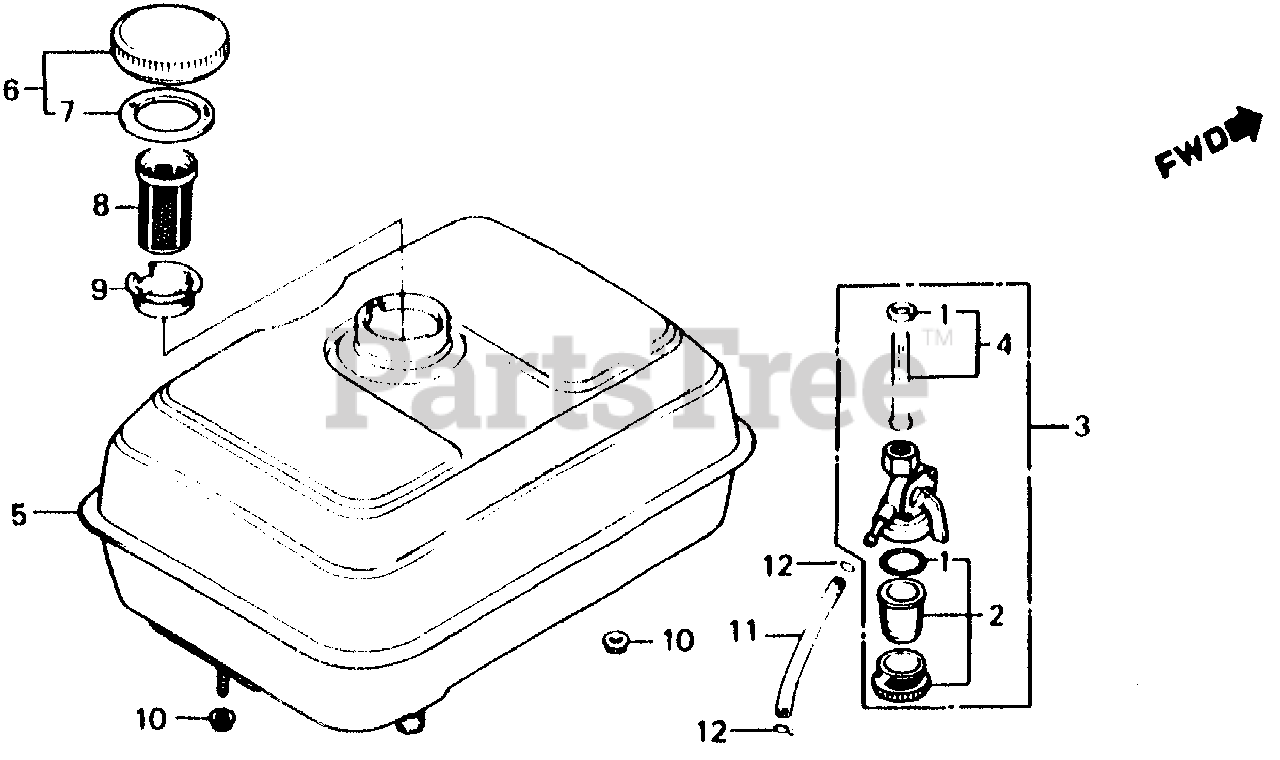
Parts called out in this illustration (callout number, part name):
1	GASKET SET, PETCOCK (CONTAINS 1 LARGE & 1 SMALL. USE AS NEEDED)
2	CUP, FUEL STRAINER
3	PETCOCK ASSY.
4	SCREEN SET
5	TANK, FUEL *NH31* (MCKINLEY WHITE)
6	CAP, FUEL FILLER
7	GASKET, FUEL FILLER CAP
8	FILTER, FUEL
9	HOLDER, FUEL FILTER
10	NUT, FLANGE (6MM)
11	BULK HOSE, FUEL (4.5X3000) (4.5X70)
12	CLIP, TUBE (B8)
